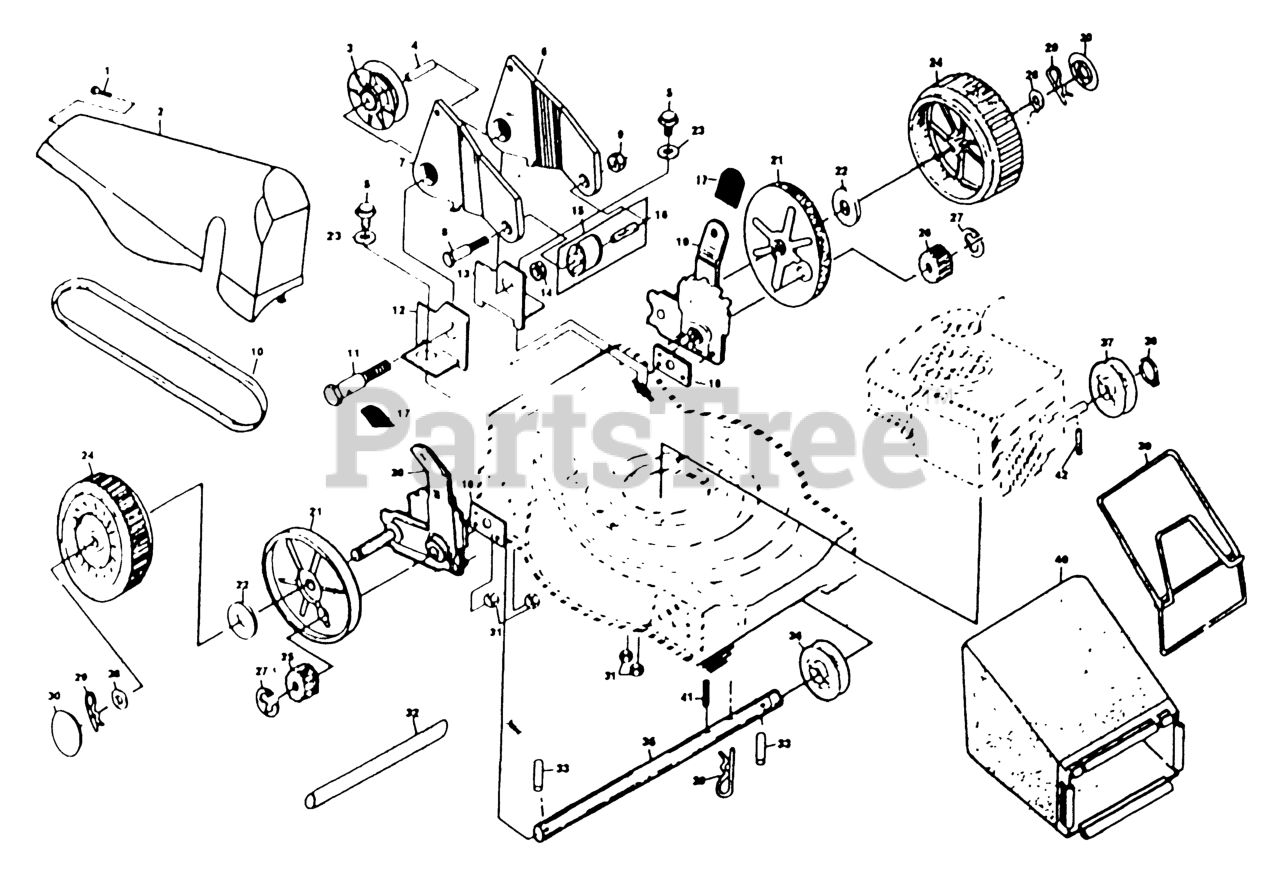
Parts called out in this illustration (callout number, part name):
1	TAPPING SCREW
2	DRIVE COVER
3	IDLER PULLEY
4	PULLEY SPACER
6	IDLER BRACKET (LEFT)
7	IDLER BRACKET RIGHT
8	Hex Head Bolt 1/4-20 x 1-1/2
11	BOLT
12	PIVOT BRACKET RIGHT
13	PIVOT BRACKET LEFT
14	LOCKNUT
15	KIT, IDLER ASSY
16	IDLER SPACER
18	SPACER PLATE
19	SELECTOR ASSY NLA
20	SELECTOR ASSY
21	DUST SHROUD PM
22	WASHER FLUT
23	FLAT WASHER
24	WHEEL&TIRE ASS'Y
25	DR PINION RH
26	DR PINION LH
28	WASHER
29	RETAINER CLIP PM
31	NUT
32	DR SHAFT CVR NLA
33	DRIVE PAWL
35	DRIVE SHAFT
36	DRIVE PULLEY PM
38	RETAINING RING ST
39	CATCHER FRAME
40	GRASS BAG
41	ROLL PIN PM
42	DOWEL PIN
